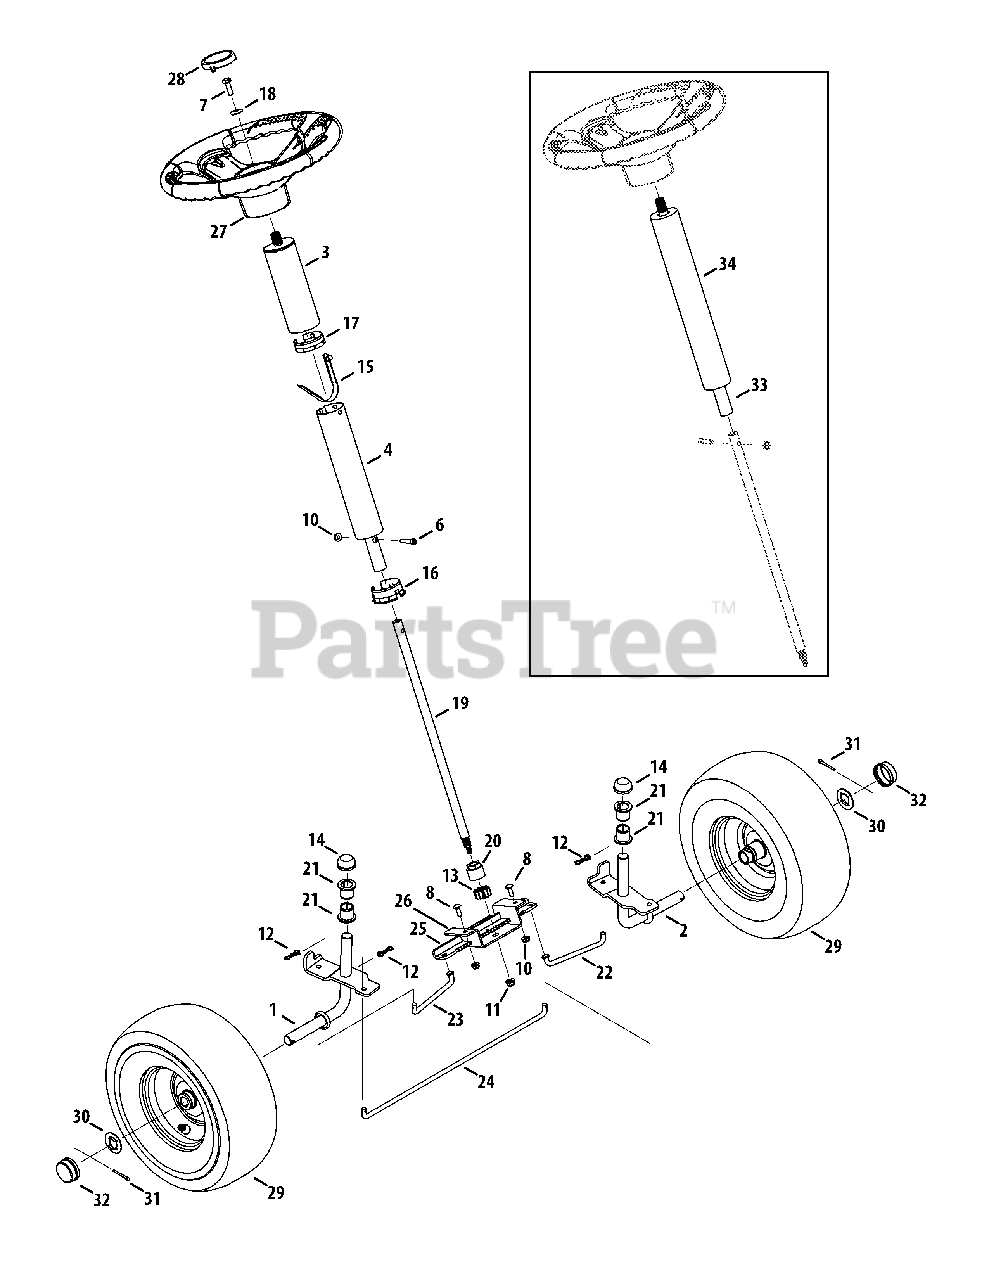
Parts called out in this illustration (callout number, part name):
1	Front Axle Assembly, RH
2	Front Axle Assembly, LH
3	Upper Tube Assembly
4	Lower Tube Assembly
6	Shld. Screw .375 x .148 :1/4-20
7	Hex Head Screw 5/16-18 x 1.00
8	Carriage Screw 1/4-20 x .75
10	Flange Lock Nut 1/4-20
11	Flange Lock Nut 5/16-18
12	Bow-Tie Cotter Pin
13	Steering Pinion Gear
14	Push Cap 3/4
15	Snap Butt
16	Lower Steering Collar
17	Upper Steering Collar
18	Cupped Washer .340 x .872 x .060
19	Steering Shaft .625 OD x 18.03
20	Hex Flange Bearing 5/8
21	Flange Bearing .760 x .941 x 1.0
22	Steering Rod, LH
23	Steering Rod, RH
24	Front Tie Rod
25	Steering Rack Plate
26	Lower Steering Bearing
27	Steering Wheel, Std. Grip
27	Steering Wheel, Soft Grip
28	Cap, std.
29	Complete Wheel Assembly
30	Washer .781 x 1.59
31	Cotter Pin 5/32 x 1.25
32	Hub Cap
33	Tube Assembly, Non-Telescoping
34	Steering Sleeve
